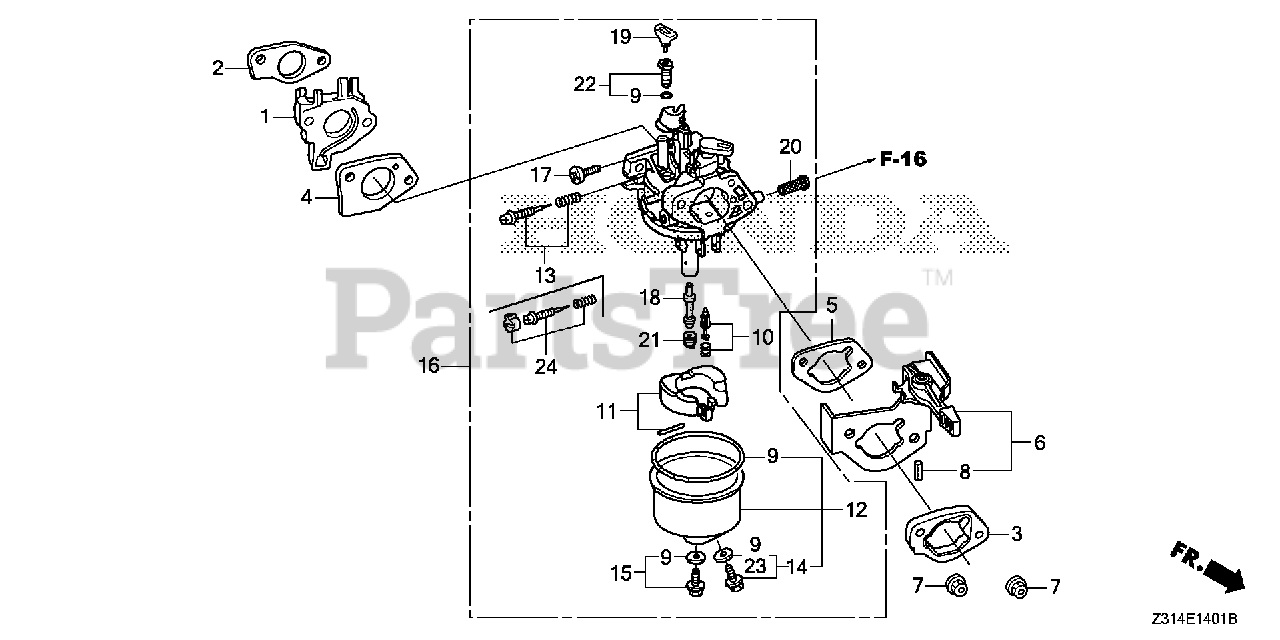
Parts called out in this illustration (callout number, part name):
1	INSULATOR, CARBURETOR
2	GASKET, CARBURETOR INSULATOR
3	SPACER, CARBURETOR
4	GASKET, CARBURETOR
5	GASKET, AIR CLEANER
6	BASE, CHOKE
7	NUT, FLANGE (6MM)
8	PIN, SPRING (2X12)
9	GASKET SET
10	VALVE SET, FLOAT
11	FLOAT SET (CARBURETOR NO.)
12	CHAMBER SET, FLOAT
14	SCREW SET, DRAIN (Honda Code 1672187). (CARBURETOR NO.)
15	SCREW SET
16	CARBURETOR ASSY. (BE95L A)
17	SCREW, THROTTLE STOP
18	NOZZLE, MAIN
19	COLLAR, SET
20	SCREEN, FUEL STRAINER
21	JET, MAIN (#100) Use from Engine SN BE87A A to BE87A A.
21	JET, MAIN (#102) (ADVENTURE GREEN) (CARBURETOR NO.)
21	JET, MAIN (#108) (CARBURETOR NO.)
22	JET SET, PILOT (#38)
23	WASHER, PLAIN (6.2X10.7 DRAIN) (CARBURETOR NO.)
24	SCREW SET (Honda Code 4219879). (CARBURETOR NO.)
